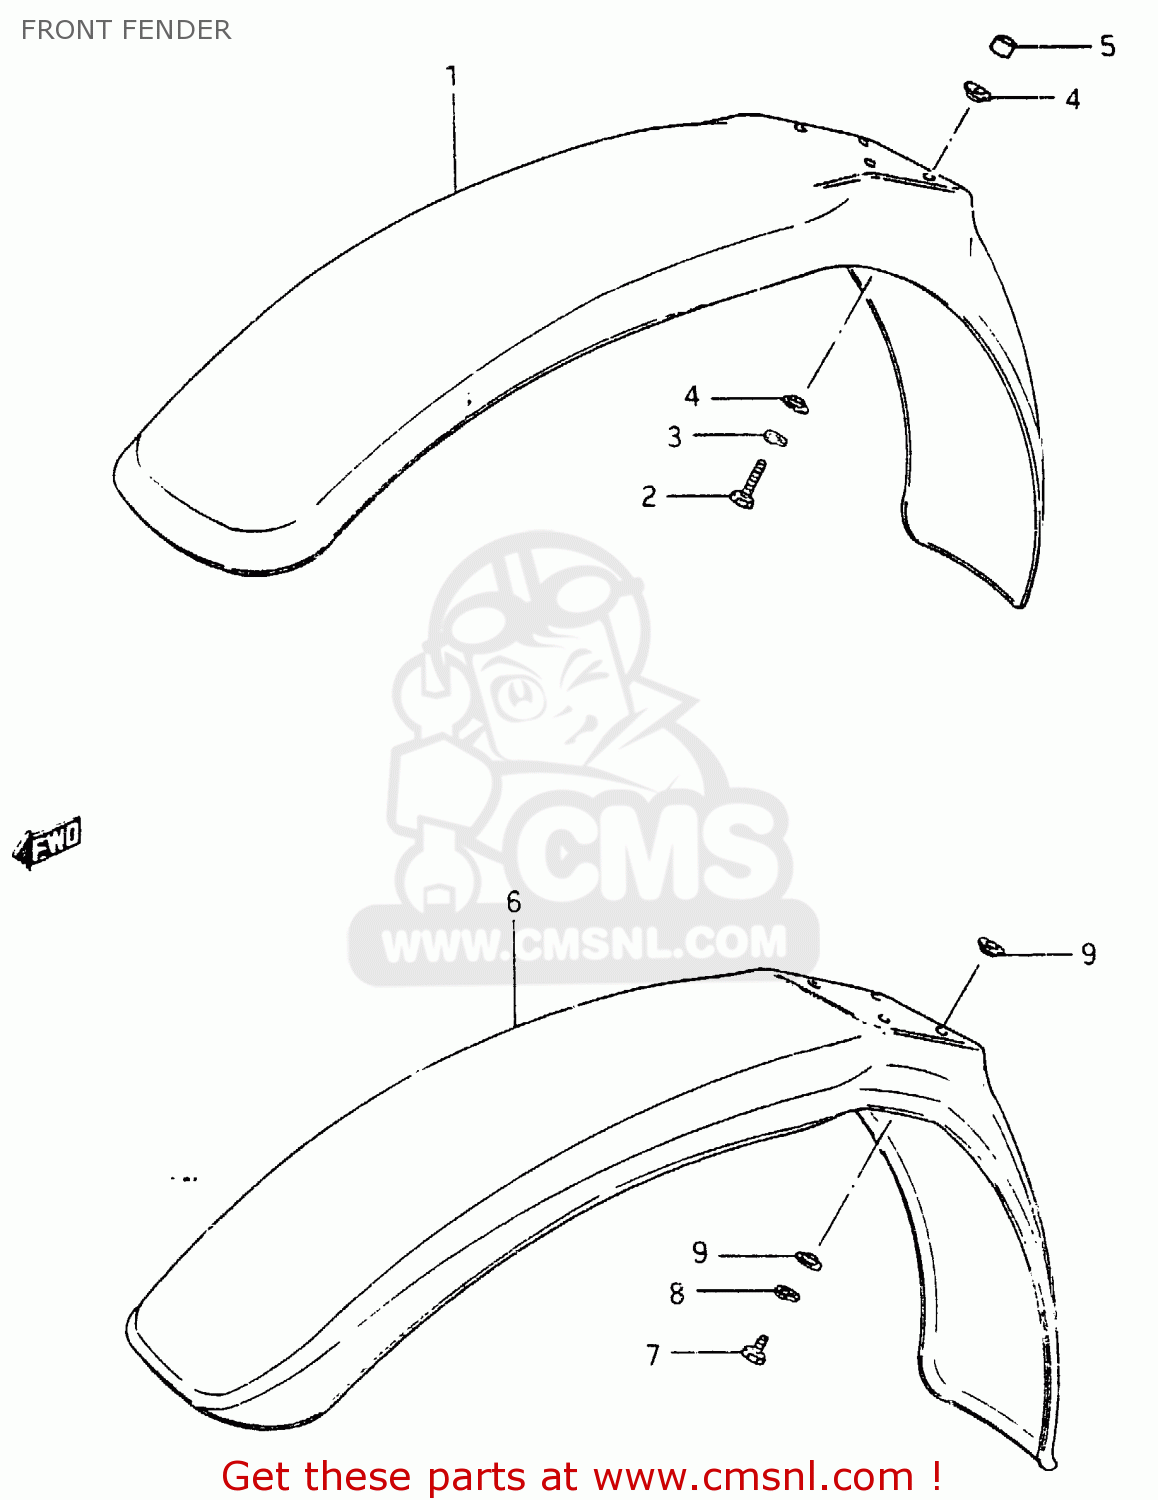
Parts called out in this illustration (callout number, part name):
1	FENDER,FRONT
2	BOLT
3	LOCK WASHER
4	WASHER
5	SPACER FRONT FENDER
6	FENDER,FR
7	BOLT, UPPER
8	LOCK WASHER
9	SPACER
